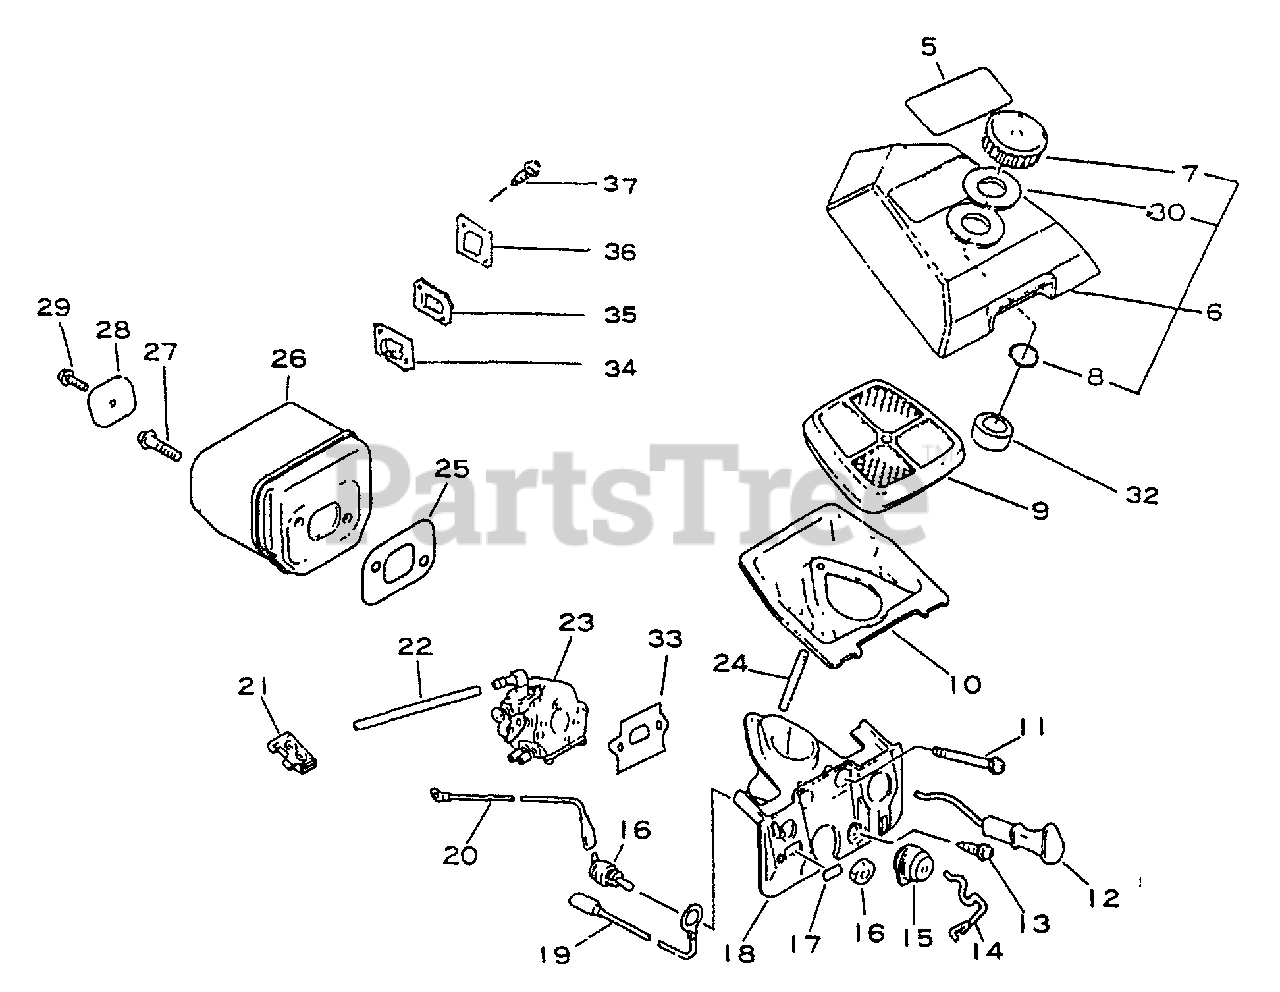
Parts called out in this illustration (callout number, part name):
5	LABEL - MODEL
6	AIR FILTER COVER ASSY
7	THUMBNUT
8	O-RING - 11
9	AIR CLEANER ASSY
10	CASE, AIR FILTER
11	SCREW - 5X55
12	ROD, CHOKE
13	SCREW - 5X20
14	ROD, THROTTLE
16	IGNITION SWITCH ASSY
17	LABEL - SWITCH
18	BRACKET, AIR CLEANER
22	PIPE - FUEL
23	CARBURETOR WT-118A
25	GASKET, EXHAUST
27	SCREW - 5X18
28	PLATE
29	SCREW - 4X8
32	CAP, INSIDE
33	GASKET, INTAKE
34	SCREEN, SPARK ARRESTOR
35	GUIDE, EXHAUST
36	BAFFLE, MUFFLER
37	SCREW - 4X8
